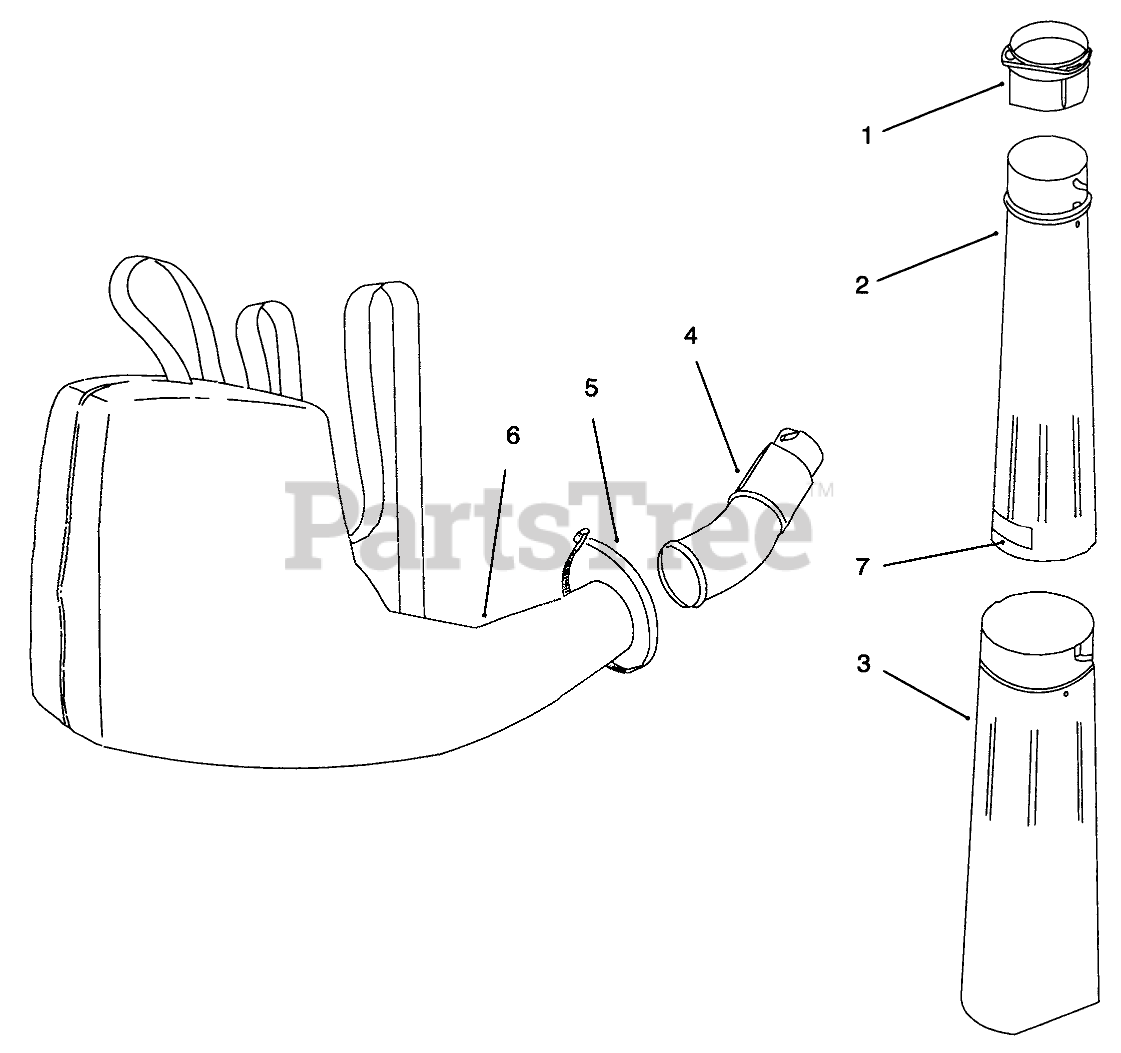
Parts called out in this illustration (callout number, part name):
1	ADAPTER - VAC TUBE
2	VACUUM-UPPER TUBE/ADAPTER
3	TUBE - LOWER VACUUM
4	ELBOW
5	Clamp
6	Vacuum Bag Asm. (Incl. Ref. #3 and 4)
7	DECAL - WARNING
